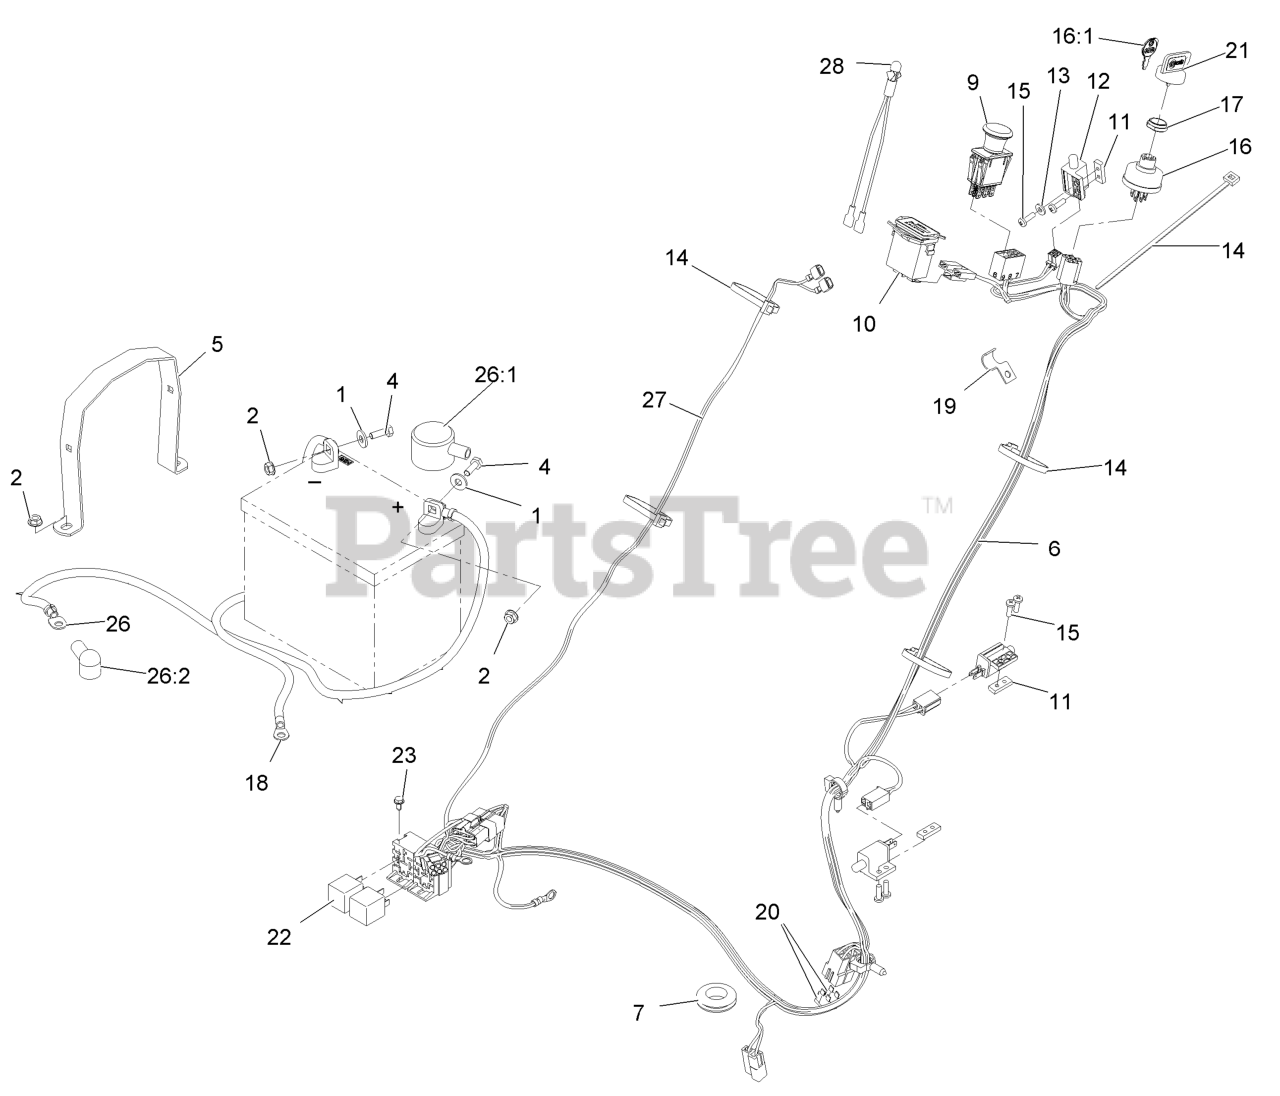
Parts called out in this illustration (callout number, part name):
1	WASHER-FLAT
4	SCREW-HH
5	STRAP,BATTERY HOLDDOWN
7	GROMMET
9	SWITCH-PTO
10	METER-HOUR
11	PLATE-TAPPED
12	SWITCH-OPEN, NORMALLY
13	WASHER-FLAT
14	TIE-PLASTIC
15	SCREW-PPH
16:1	KEYS-IGNITION (SPARE PAIR
17	NUT-SWITCH, IGNITION
18	WIRE-GROUND
19	CLIP-HALF, LOOM
20	FUSE-BLADE TYPE, 20 AMP
21	KEY-IGNITION
23	SCREW-HWH
26	POSITIVE BATTERY CABLE AS
26:1	INSULATOR-BATTERY
26:2	INSULATOR-SOLENOID
27	HARNESS, MIL
28	INDICATOR-LED, RED
